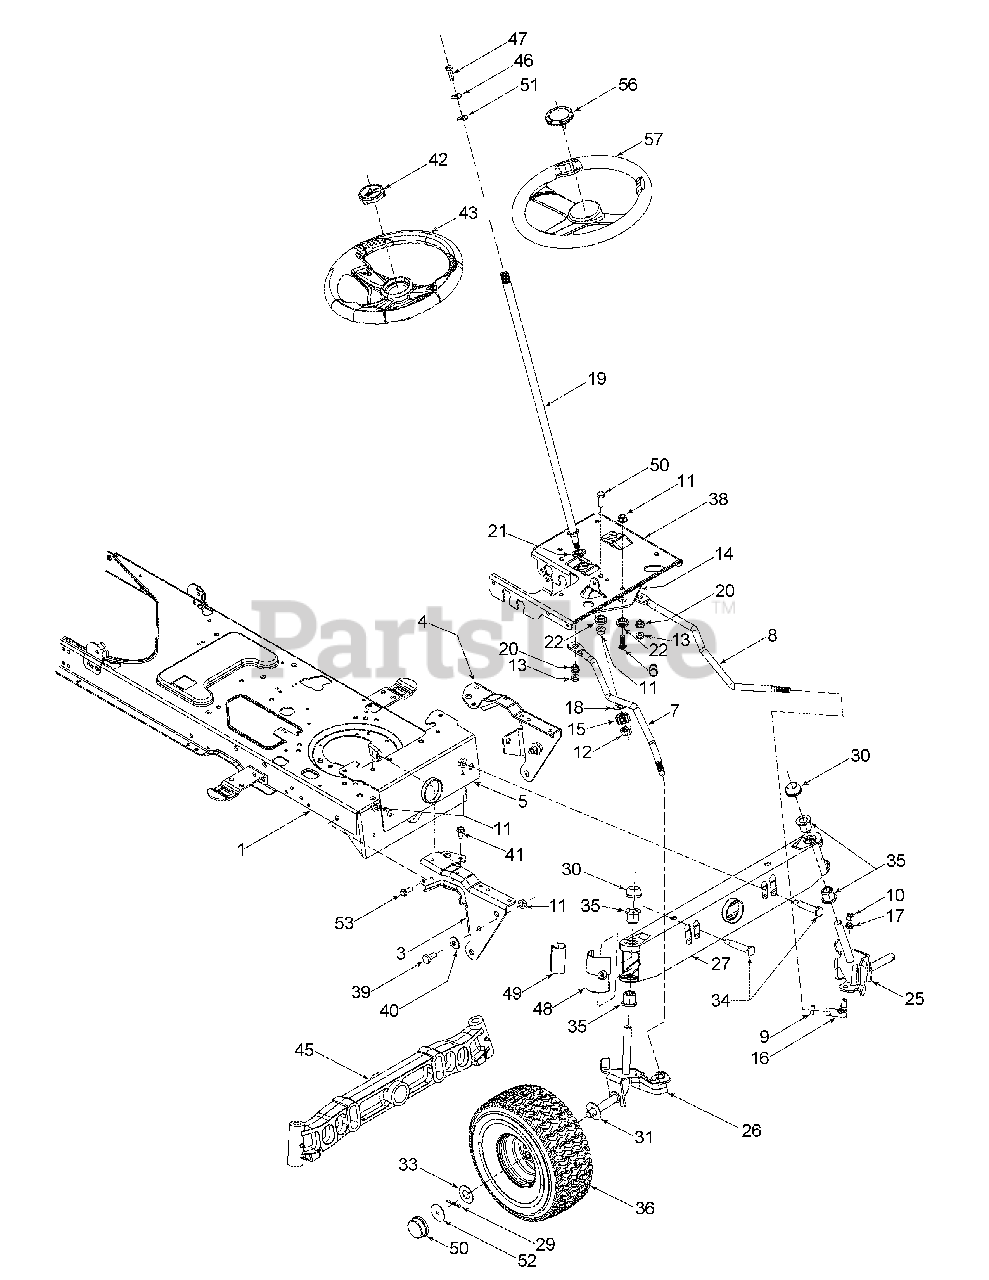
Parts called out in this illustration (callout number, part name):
6	Hex Cap Screw, 3/8-16 x 1.0
7	RH Drag Link
8	LH Drag Link
9	Jam Nut, 7/16-20
10	Hex Nut, 3/8-24
11	Flange Lock Nut, 3/8-16
12	Flange Lock Nut, 7/16-20
13	Flange Lock Nut, 5/16-18
14	Steering Gear, 11/90 Ratio
15	Steering Pinion Gear
16	Ball Joint, 7/16-20
17	Lock Washer, 3/8
18	Flat Washer, .51 x 1.12 x .06
19	Steering Shaft, .625 OD x 24.4
20	Plastic Bushing, .38 ID
21	Hex Flange Bearing, 5/8
22	Shoulder Spacer, .38 ID
25	LH Axle Assembly - 42" Deck
25	LH Axle Assembly .750
26	RH Axle Assembly - 42"Deck
26	RH Axle Assembly .750
29	Cotter Pin
30	Push Cap, .625
30	Push Cap, .75
31	Flat Washer .781 ID x 1.59 OD
33	Flat Washer, .635 x 1.589 x .06
34	Shoulder Screw, .5 x 2.2, 3/8-16
35	Flange Bearing, .76 ID x .937 OD
39	Shoulder Screw, 3/8-16
40	Bell Washer, .39 x 1.13 x .062
41	Self-tapping Screw, 5/16-18 x .75
42	Steering Wheel Cap
43	Steering Wheel, Soft Grip
45	Cast Iron Pivot Bar (includes 748-04068)
46	Bell Washer, .34 x .872
47	Hex Bolt, 5/16-18 x 1.0
48	Pivot Bar End Cap w/ Fitting
51	Flat Washer, .406 x .875 x .105
52	Flat Washer, .35 x 1.59 x .062
53	Screw, Hex Washer, 5/16-18 x .87
56	Steering Wheel Cap
57	Steering Wheel, Soft Grip
